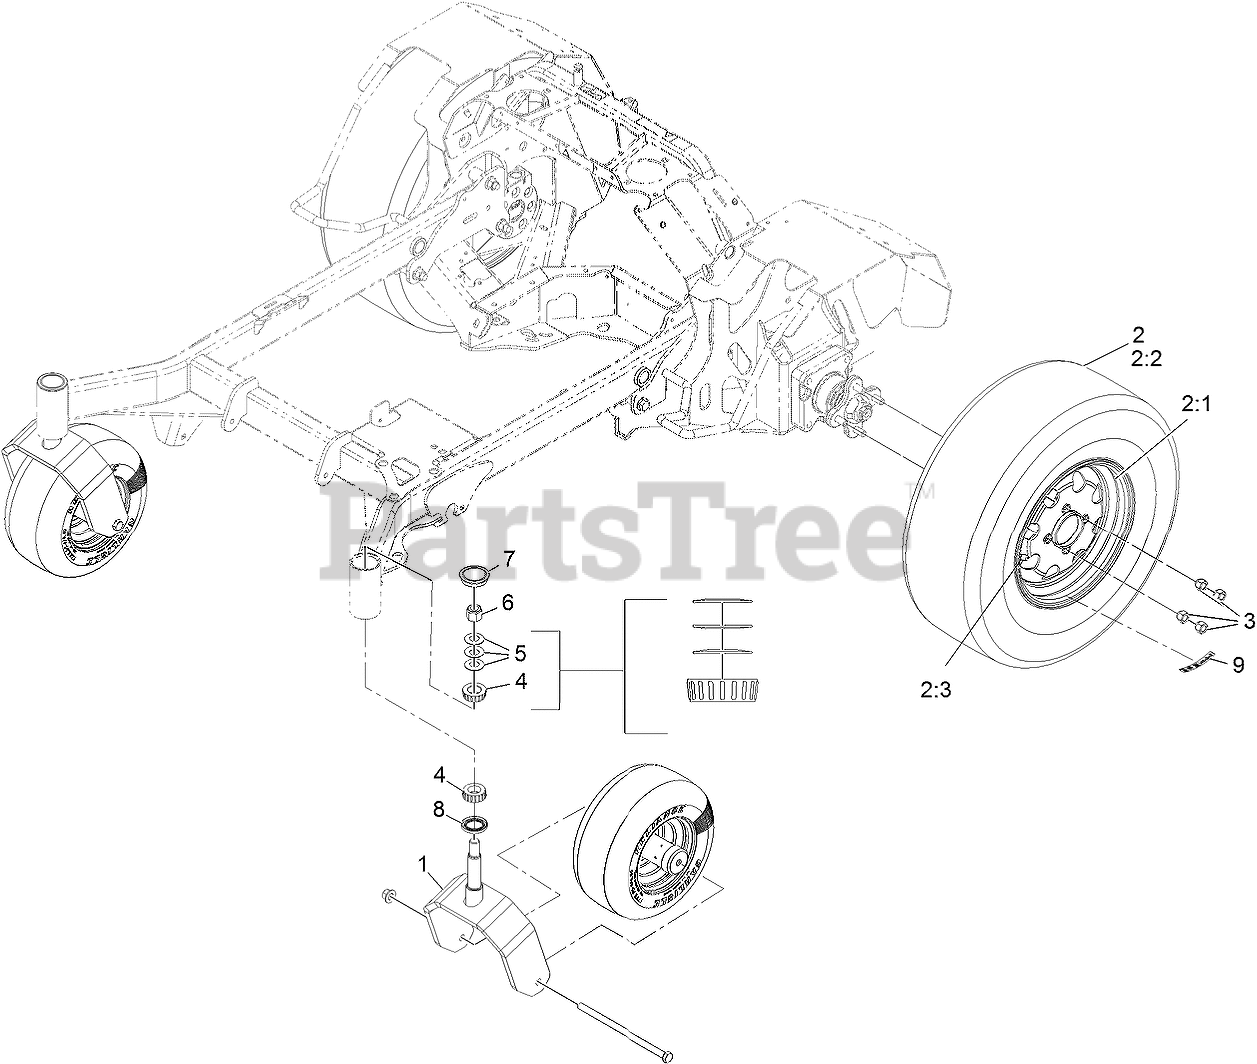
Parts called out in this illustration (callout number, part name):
2	ASM, Wheel And Tire
2:1	RIM ASM
2:2	Tire, 23 X 8.50-12
2:3	Stem-Valve
3	NUT-LUG
4	Cone-Bearing Tapered Roller
5	WASHER-BELLVILLE
6	NUT-LOCK, NI
7	CAP-GREASE
8	SEAL-GREASE
9	DECAL-TORQUE, WHEEL HUB LUG
